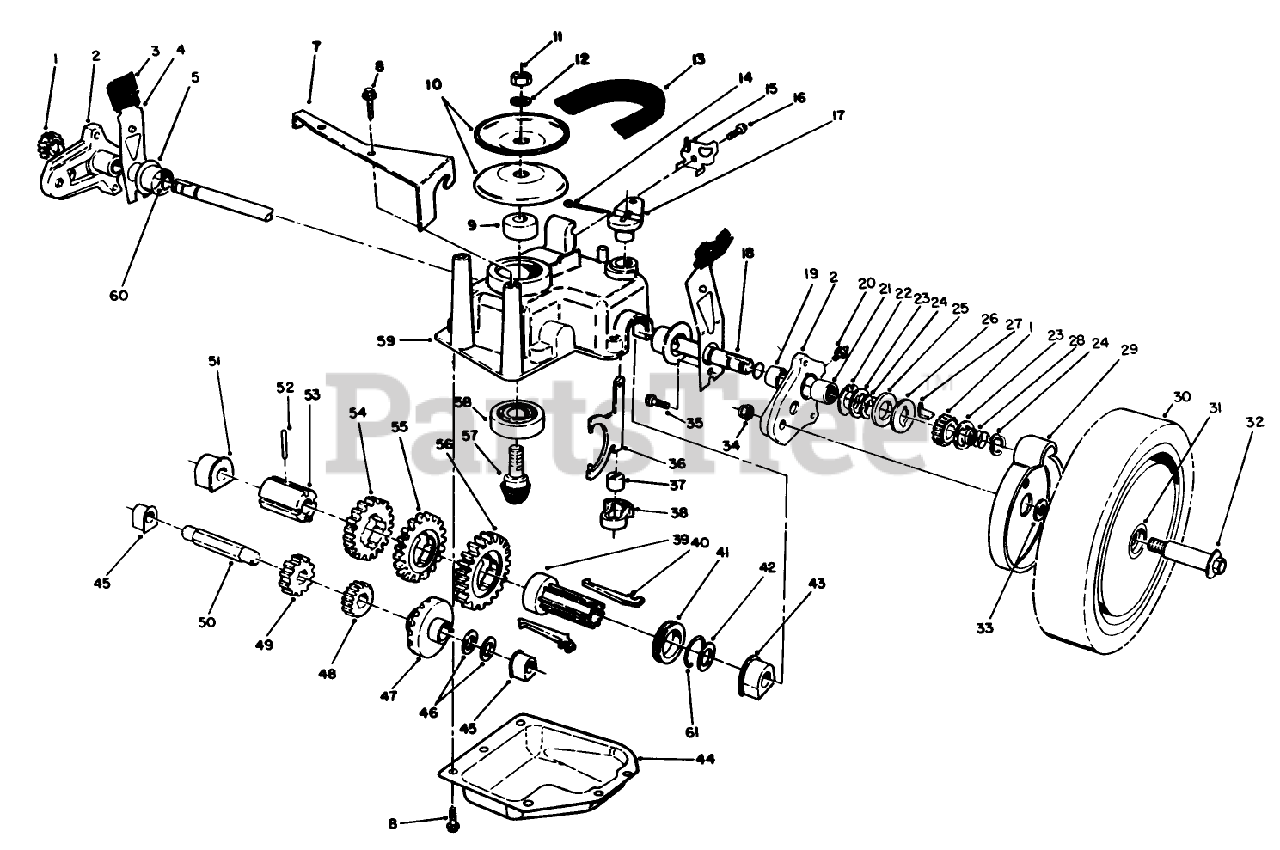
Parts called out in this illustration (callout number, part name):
1	GEAR-PINION
2	PIVOT ARM ASM
3	KNOB-ARM
4	SPRING ARM ASM SP
5	CAP-END
8	SCREW-HWHTF
9	SPACER
11	NUT-HEX
12	WASHER-FLAT
13	V-BELT
14	PIN-COTTER
15	CLAMP-CABLE
16	SCREW-HWHTF
17	LEVER-SHIFT
18	SHAFT-OUTPUT
19	BUSHING
20	FITTING-GREASE
22	WASHER-ARM, PIVOT
23	WASHER-THRUST, KEYED
24	RING-RETAINING,CLIP
25	RING-FRICTION
26	WASHER-CLUTCH
27	KEY-ROCKING, LH
28	SPRING-COMPRESSION
29	COVER-WHEEL
31	BUSHING
32	WHEEL BOLT
33	SPACER-COVER, WHEEL
35	SCREW-HWH
36	YOKE-SHIFT
37	BUSHING-YOKE
38	RETAINER-FORK, SHIFT
39	SLEEVE-KEY, SHIFT
40	KEY-SHIFT
41	COLLAR-SHIFT
42	WASHER-PLAIN
43	BUSHING-OUTPUT
45	BUSHING
46	WASHER-THRUST
48	PINION-20T
49	PINION-25T
51	BUSHING
52	PIN-ROLL
53	SLEEVE-GEAR
54	GEAR-39T
55	GEAR-44T
56	GEAR-49T
58	BEARING-BALL
59	CASE-GEAR, UPPER
60	O-RING
61	CLIP-SPRING
